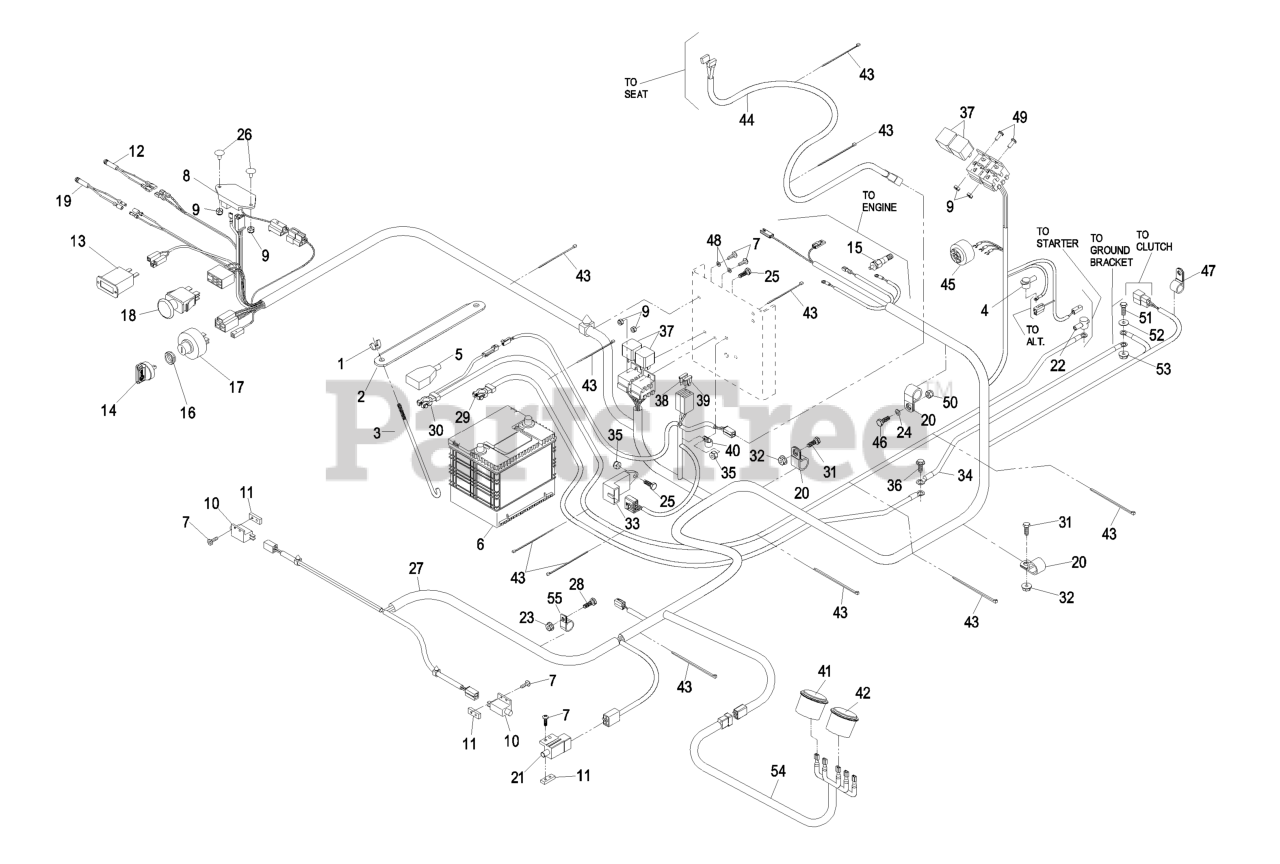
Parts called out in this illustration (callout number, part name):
1	WINGNUT
2	HOLDDOWN-BATTERY
3	BOLT-HOLDDOWN
4	CAP-INSULATOR, RED
5	INSULATOR-TERMINAL, BATTE
6	Battery, 12v SAE Post
7	SCREW-PPH
8	MODULE-DELAY, SEAT
9	NUT-LOCK, NI
10	SWITCH-OPEN, NORMALLY
11	PLATE-TAPPED
12	INDICATOR-LED, RED
13	METER-HOUR
14	KEY-IGNITION
15	SENDER-TEMPERATURE
16	NUT-SWITCH, IGNITION
18	SWITCH-PTO
19	INDICATOR-LED, AMBER
20	CLIP-LOOM
22	INSULATOR-STARTER
24	WASHER-FLAT
25	SCREW-HH
26	BOLT-CARR
27	HARNESS-WIRE
28	SCREW-HH
29	CABLE-BATTERY NEGATIVE
30	CABLE-STARTER
31	SCREW-HH
33	Briggs & Stratton P/N 820373 Module, Pre-Heat Timer
34	CABLE-ENGINE NEGATIVE
35	NUT-LOCK, NI
36	Screw-HWH 5/16-18 X 3/4 Tf
38	FUSE-BLADE TYPE, 20 AMP
39	FUSE-40 AMP
40	CLIP-LOOM
41	GAUGE-VOLTMETER
42	GAUGE-TEMPERATURE
43	TIE-PLASTIC
44	HARNESS-WIRING, SEAT
45	ALARM-TONE, DUAL
46	SCREW-HH
47	CLIP-LOOM
48	WASHER-FLAT
50	NUT-LOCK
51	SCREW-HH
52	WASHER-FLAT
53	NUT-HHF, WHIZ
54	HARNESS-GAUGE
55	CLIP-LOOM
